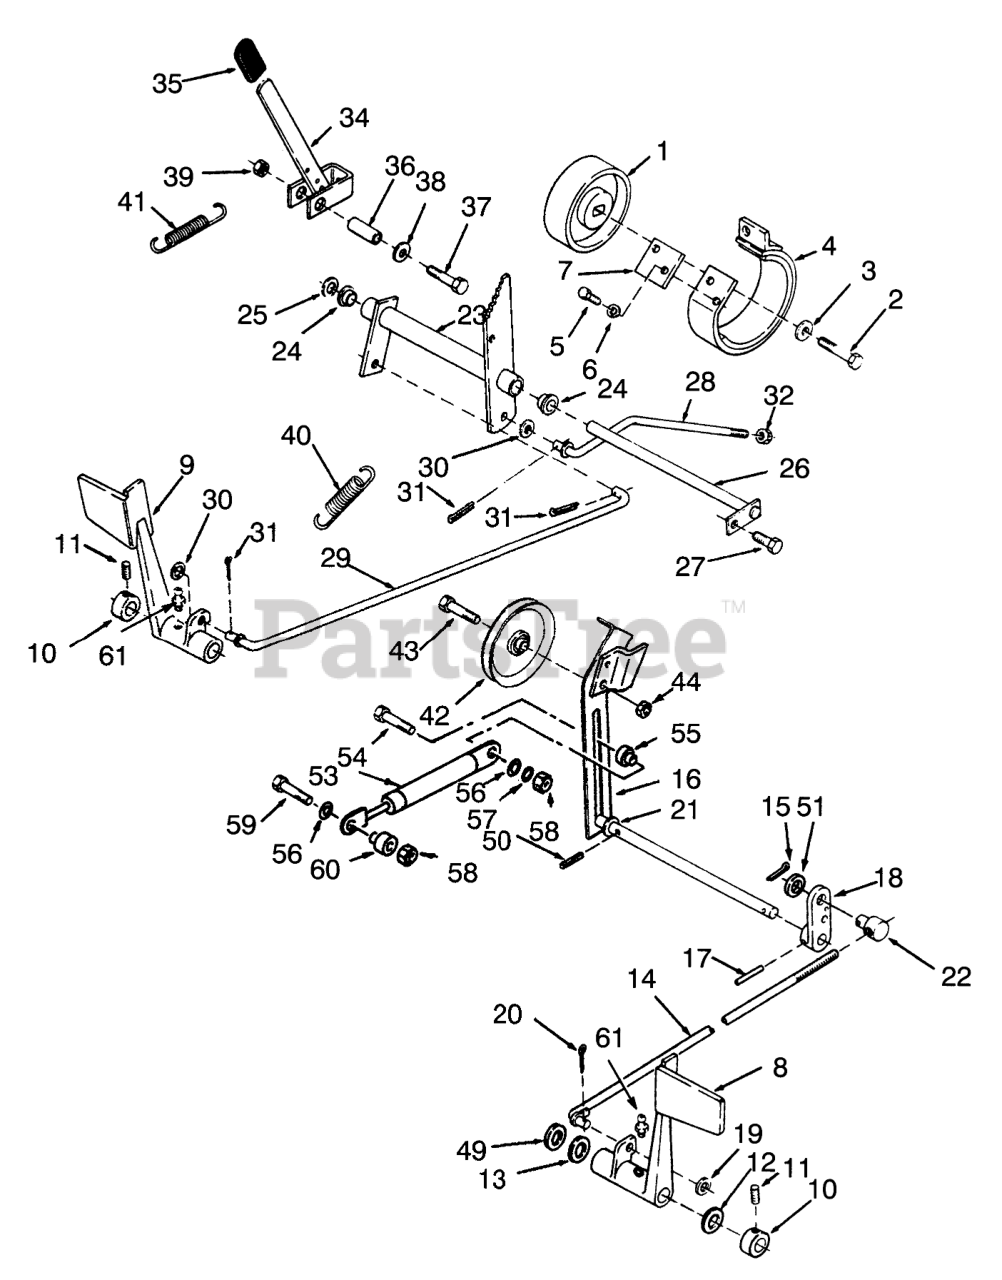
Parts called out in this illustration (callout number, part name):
1	DRUM-BRAKE
2	SCREW-HEX HD CAP
3	WASHER
4	BRAKE BAND ASM
5	SCREW-HH
6	WASHER-LOCK
7	Plate-Stop
8	PEDAL-CLUTCH R
9	Pedal-Brake
10	COLLAR
11	SCREW-HSH
12	WASHER-BOWED
13	WASHER
14	ROD AND GUIDE ASM
15	PIN-COTTER
16	Arm-Clutch Idler
17	PIN-SPIROL
18	Arm-Clutch Rod
19	WASHER-NYLON
20	PIN-COTTER
21	SHIM-WASHER
22	TRUNNION
23	Bellcrank Assy
24	BUSHING-FLANGED
25	WASHER-FLAT
26	ROD ASM
27	Bolt
28	ROD-REAR BRAKE
30	WASHER-NYLON
31	PIN-COTTER
32	NUT-LOCK, NI
34	ASSY-BRAKE LEVER WAB
35	GRIP
36	SPACER
37	SCREW-HH
38	WASHER-FLAT
39	LOCKNUT-FLANGE
40	SPRING-BRAKE
41	SPRING-EXTENSION
42	PULLEY-IDLER
43	BOLT-SPECIAL HEX
44	NUT-LOCK, NI
49	WASHER
50	PIN-SPIROL
51	WASHER-FLAT
53	ASS'Y-GAS SPRING
54	SCREW-HH
55	SPACER-SHOULDER-.200
56	WASHER-FLAT
57	WASHER-LOCK
58	NUT-LOCK, NI
59	SCREW-HH
60	SPACER-SHOULDER-.400
61	FITTING-GREASE
